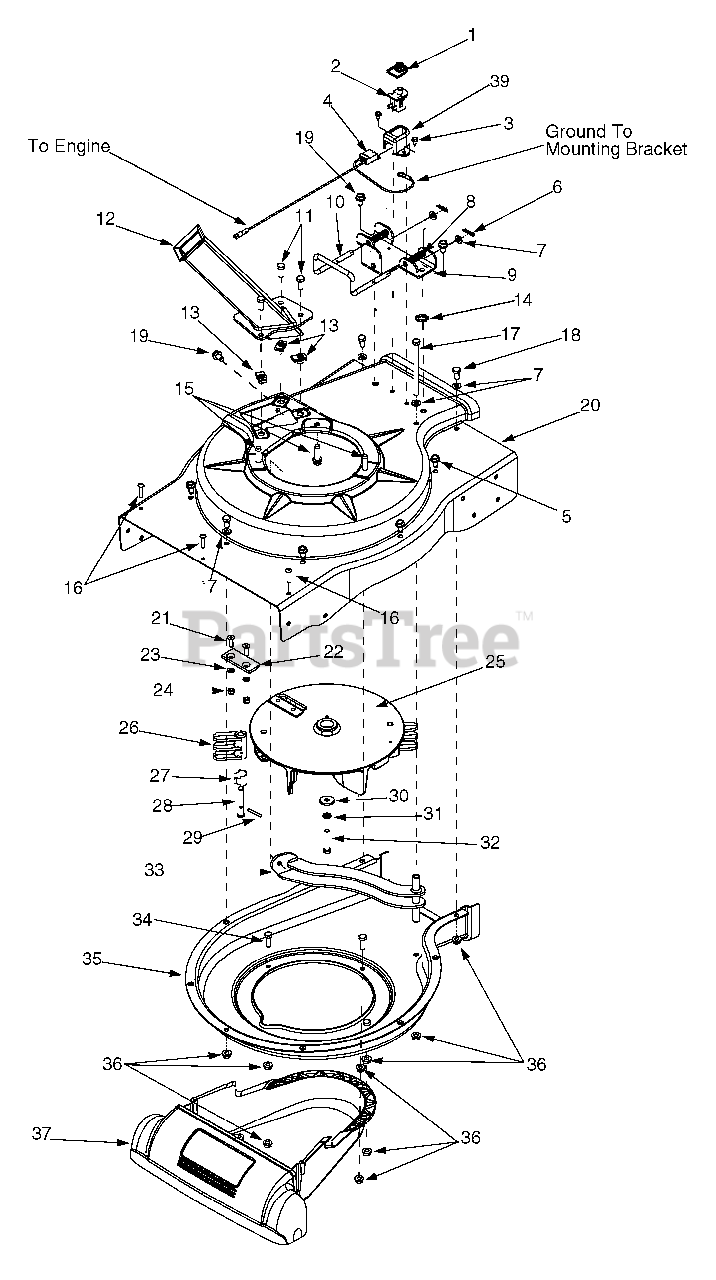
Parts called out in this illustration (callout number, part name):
1	Switch Cover
2	Safety Switch
3	Hex Washer Screw #10-16 x.50
4	Wire Harness
6	Cotter Pin
7	Flat Washer.330 ID x.630 OD
8	Compression Spring
10	Lock Rod
11	Hex Cap Screw 5/16-18 x.75
13	U-Clip Lock Nut 5/16-18
14	External Lock Washer 5/16
15	Hex Washer Screw 3/8-16 x 1.25
16	Screw #12-16 x 1.0
17	Hex Cap Screw 5/16-18 x 4.5
18	Hex Cap Screw 5/16-18 x.625
19	Hex Washer Screw 5/16-18 x.625
22	Chipper Blade
23	Lock Washer 5/16
24	Hex Lock Nut 5/16-24
25	Impeller Assembly
26	Flail Blade
27	Pin Clip
28	Clevis Pin
29	Spiral Pin
30	Flat Washer.375 ID x 1.25 OD
31	Lock Washer 3/8
32	Hex Cap Screw 3/8-24 x 2.0
34	Hex Cap Screw 5/16-18 x.875
36	Lock Nut 5/16-18
37	Nozzle Cover
39	Safety Switch Cover
